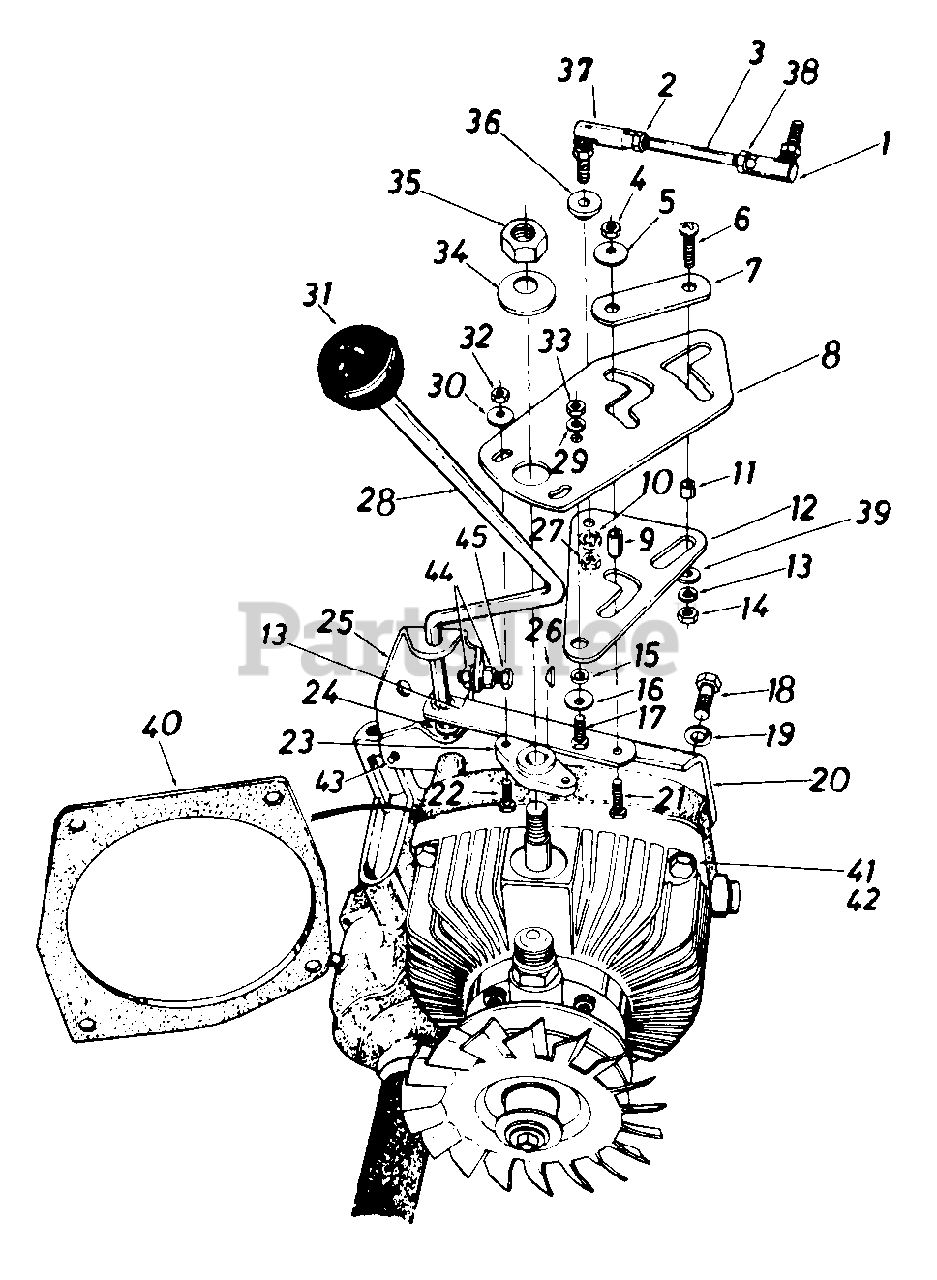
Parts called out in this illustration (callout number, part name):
1	Ball Joint Ass'y. 3/8-24 Thd.
2	Hex Nut 3/8-24 Thd. (L.H. Threads)
3	Control Rod 3/8-24 x 3.75"
4	Hex Nut 3/8-24 Thd.
5	Fl-Wash. .385" I.D. x .87" 0. D.
6	Truss Mach. Scr. Phil. 5/16-18 x 1.00" Lg.
7	Locking Link
8	Pintle Main Control Plate
9	Spacer .377" I.D. x .500" O.D. x .830" Lg.
10	L-Wash. 3/8" I.D.
11	Spacer .315" I.D. x .500" O.D. x .350
12	Pintle Drive Plate
13	L-Wash. 5/16" I.D.
14	Hex Nut 5/16-18 Thd.
15	Spacer .38" I.D. x .227" Lg.
16	Fl-Wash. .385" I.D. x .87" O.D.
17	Hex Bolt 3/8-24 x 1.00" Lg.
18	Hex Bolt 3/8-16 x 1.0" Lg. (Grade 5)
19	L-Wash. 3/8" I.D.
20	Shift Lever Bracket
21	Hex Bolt 3/8-24 x 1.25" Lg.
22	Hex Bolt 1/4-28 x .75" Lg.
23	Pintle Hub
24	Nyliner .375" Dia. x .140
25	Shift Lever Bracket Upper
26	#5 Hi-Pro Key 1/8 x 5/8 Dia.
27	Hex Nut 3/8-24 Thd.
28	Shift Lever Ass'y.
29	L-Wash. 3/8" I.D.
30	Fl-Wash. .385" I.D. x .87" O.D.
31	Gear Shift Knob
32	Hex Nut 1/4-28 Thd.
33	Hex Nut 3/8-24 Thd.
34	Bell-Wash. .505" I.D. x 1.00" O.D.
35	Hex Nut 1/2-13 Thd.
36	Shld. Spacer .625" I.D.
37	Ball Joint Ass'y. 3/8-24 L.H. Thd.
38	Hex Jam Nut 3/8-24 Thd.
39	Fl-Wash. .330" I.D. x 1.25" O.D.
40	Gasket
41	Hex Bolt 3/8-16 x 2.75" Lg. (Gr. 5)
43	Hex Wash. Hd. Self-Tap Scr. 1/4-20 x .50" Lg.
44	Hex Nut 5/16-24 Thd.
45	Hex Bolt 5/16-24 x 1.0" Lg.
